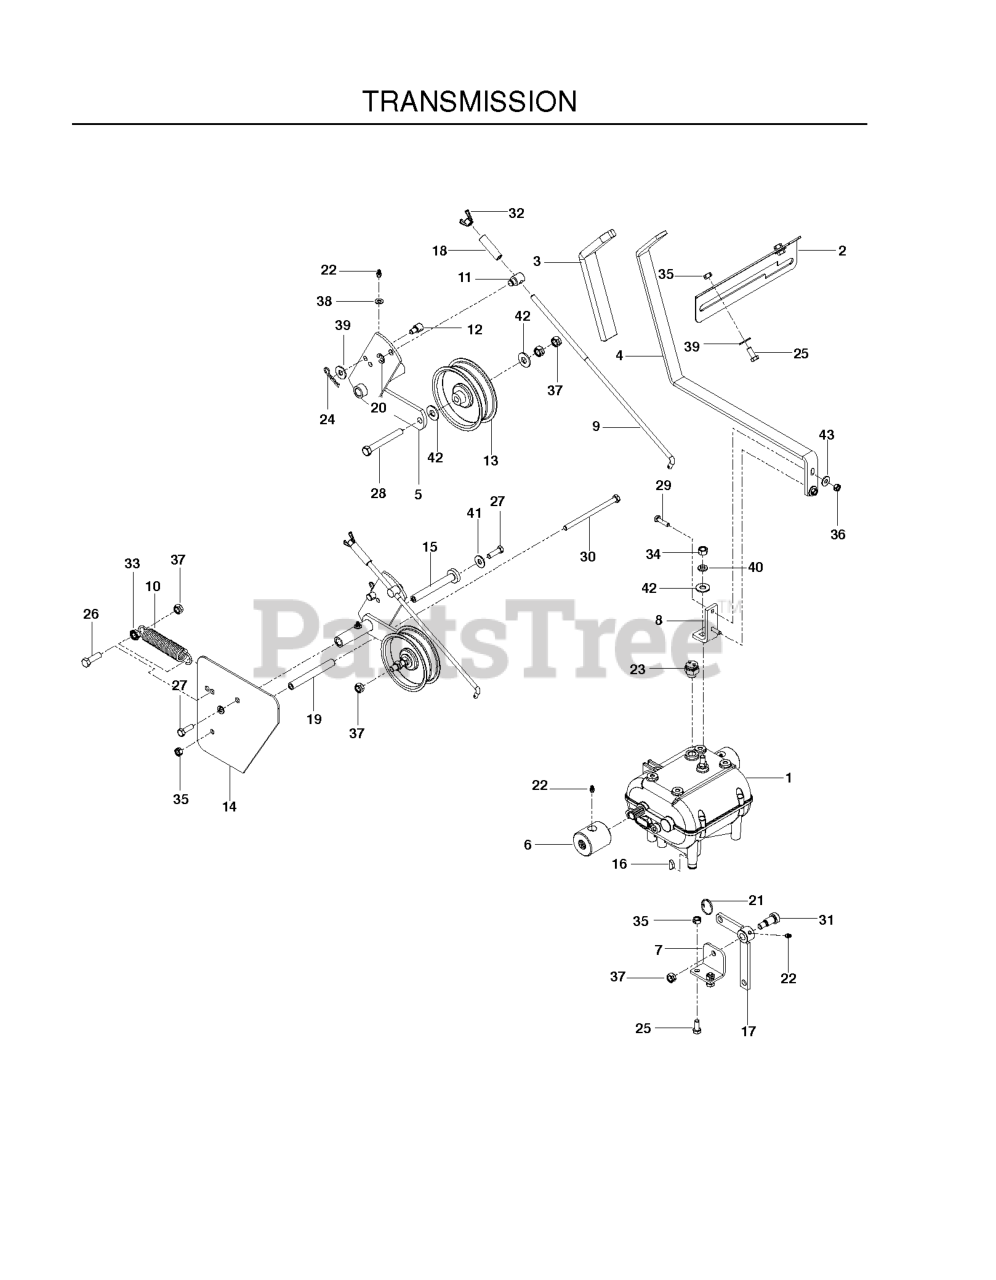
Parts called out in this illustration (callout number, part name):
1	TRANSMISSION WB
2	SHIFTER PLATE
3	SHIFTER GRIP
4	SHIFTER ARM
5	WLDMT, IDLER ARM RT, BLK
7	BRACKET-BELLCRANK-BLACK
8	SHIFTER BRACKET
12	SWIVEL (SHORT)
13	PULLEY, IDLER
15	SHOULDER PIVOT TUBE
16	KEY, #9 WOODRUFF
19	SPACER, LONG
20	E RING 3/8"
22	ZERK
23	SWITCH, TRANS
24	HAIRPIN #2
25	HCS 5/16C X 3/4
26	HCS 3/8C X 1 1/4 GR5
27	HCS 5/16C X 1
28	TAPBOLT, 3/8C X 3
29	HCS 1/4C X 1
30	HCS 5/16C X 5
31	SB 12C X 34
32	WINGNUT, 5/16C NYLOC
33	NUT 3/8C WHIZ
35	NUT 5/16C CENTERLOCK
36	NUT 1/4C CENTER LOCK
37	NUT 3/8C CENTERBLOCK
39	WASHER 5/16 FLAT
40	SLW 3/8 STD
41	WASHER.LOCK.HVY.HLCL.SPR.5/16
42	WASHER 3/8 FLAT
43	WASHER 1/4 FLAT
